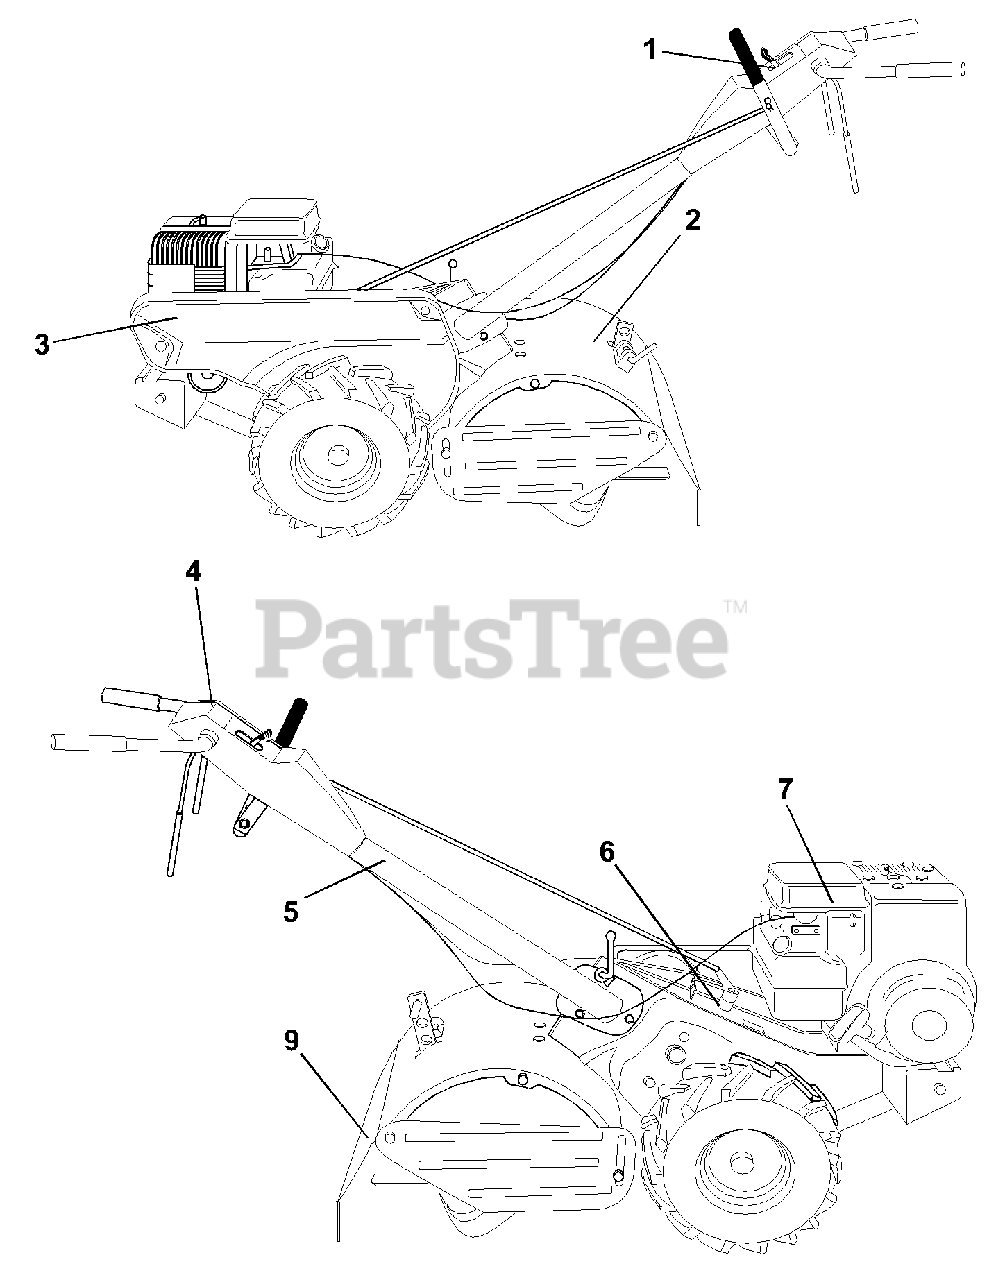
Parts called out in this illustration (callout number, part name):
1	Decal, Logo
2	Decal, Logo
3	Decal, Logo
4	Decal, Instruction, Tilling
5	Decal, Hand Placement
6	Decal, Shift Indicator
7	Decal, Caution
9	Decal, Warning, Rotating Tines
